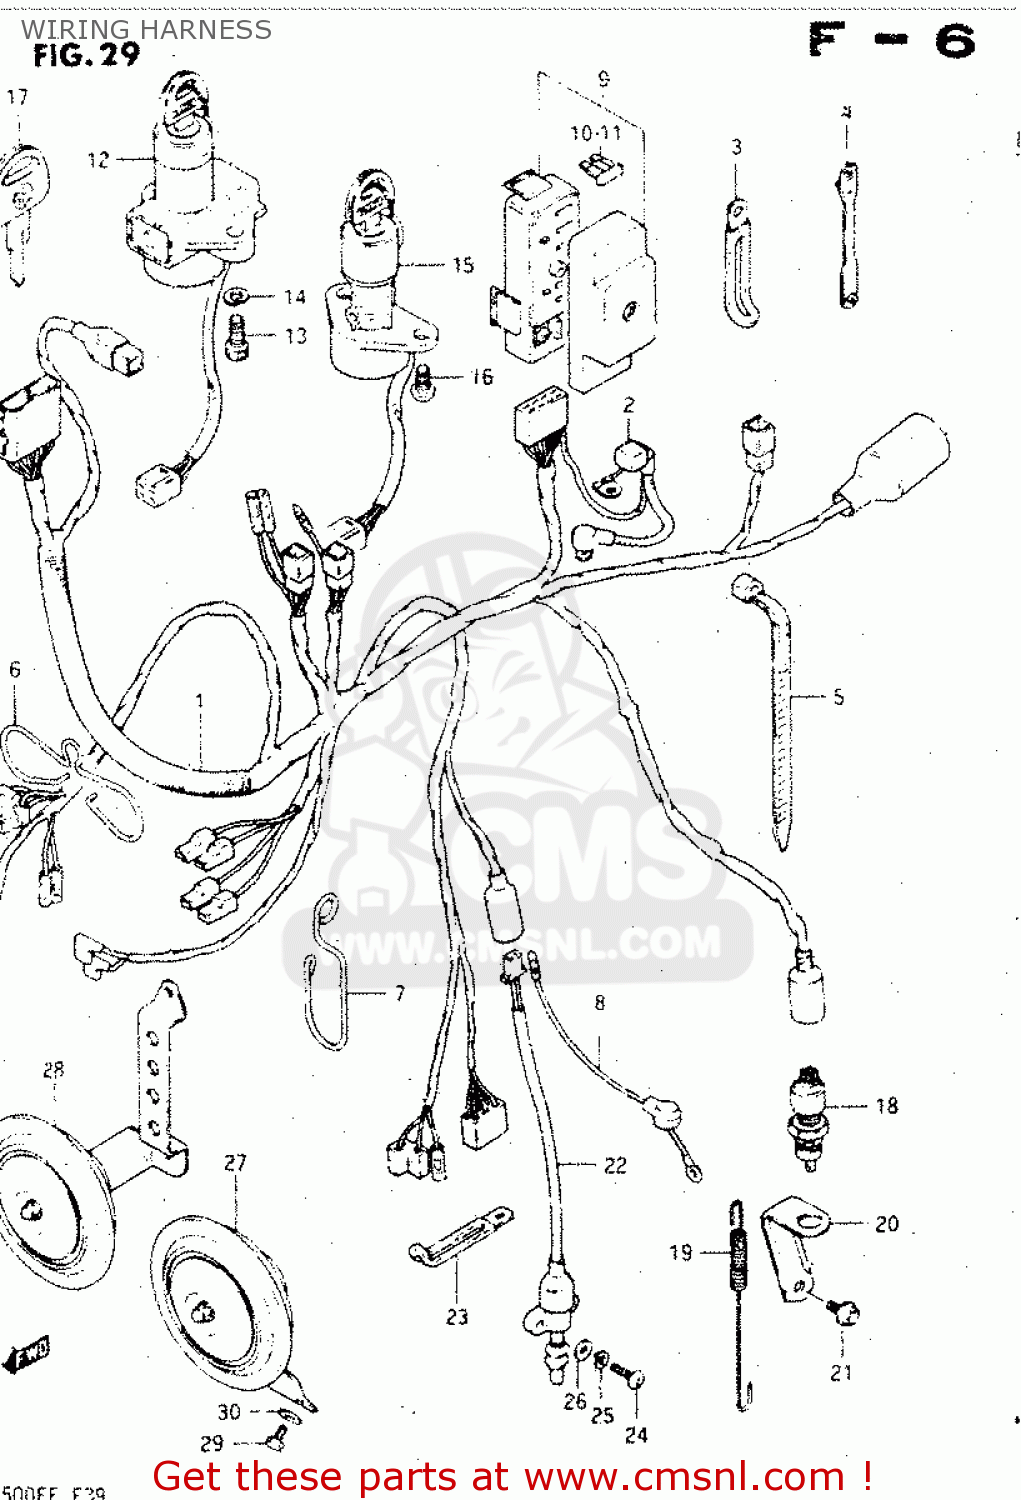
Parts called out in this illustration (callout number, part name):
1	HARNESS,WIRING
2	CAP,BATTERY PLUS TERMINAL
3	CLAMP
4	CLAMP,L:88
5	CLAMP(L:95)
6	BOOT,WIRING HARNESS
7	GUIDE,WIRING HARNESS
8	WIRE
9	FUSE BOX ASSY
10	FUSE(10A)
11	FUSE(15A)
12	IGNITION SWITCH/STEERING LOCK
13	BOLT
14	LOCK WASHER
15	SWITCH ASSY, IGNITION
16	SCREW 6X12
17	KEY,BLANK
18	SWITCH ASSEMBLY,STOP LAMP
19	SPRING
20	BRACKET,BRAKE LAMP SWITCH
21	BOLT
22	SWITCH ASSEMBLY,SIDE STAND
23	CLAMP
24	SCREW 5X20
25	WASHER,LOCK
26	WASHER,5MM
27	HORN ASSY
28	HORN ASSY
29	BOLT
30	WASHER, LOWER
